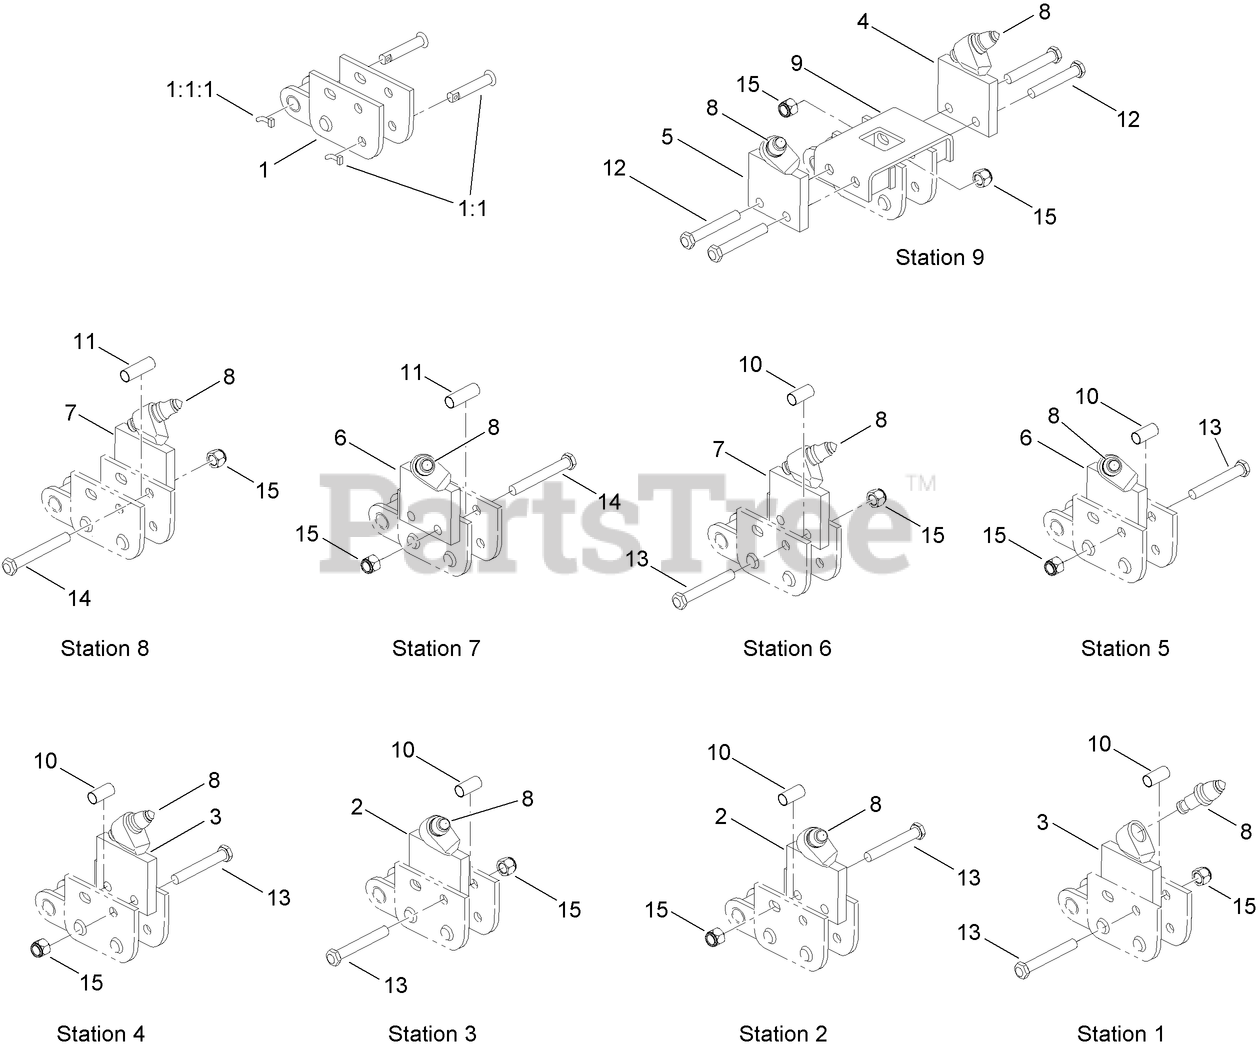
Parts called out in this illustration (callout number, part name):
1	CHAIN REPAIR LINK ASM
1:1	NOTCHED PIN AND KEEPER ASM
1:1:1	PIN-KEEPER
2	HOLDER-BIT, RH CENTER
3	HOLDER-BIT, LH CENTER
4	HOLDER-BIT, RH
5	HOLDER-BIT, LH
6	HOLDER-BIT, RH
7	HOLDER-BIT, LH
8	BIT-CARBIDE, FULL CAB
9	SADDLE-TOOTH SPREADER
10	SPACER-TUBE, INSIDE ADAPTER
11	SPACER-TUBE, OUTSIDE MOUNT
12	BOLT-HH
13	BOLT-HH
14	BOLT-HH
15	NUT-LOCK
